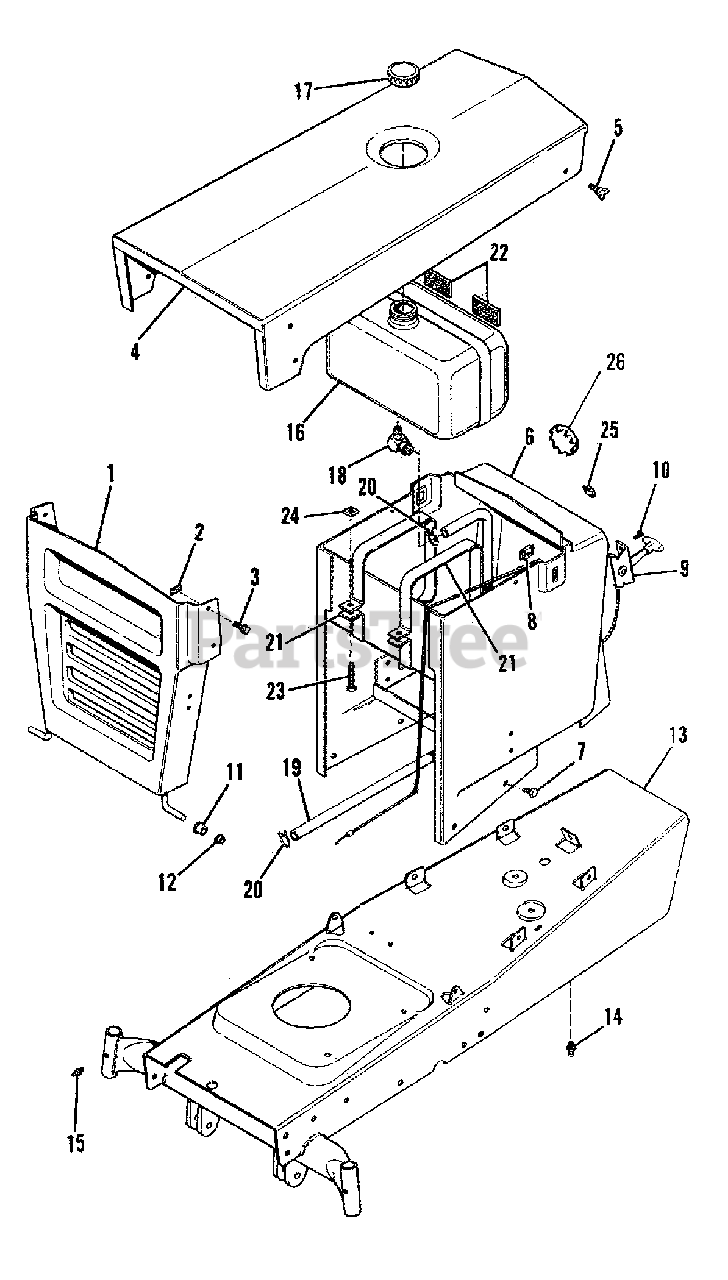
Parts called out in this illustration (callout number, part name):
1	GRILL ASSEMBLY
3	SCREW, Flange, 1/4-20 x 3/4" Large
5	SCREW, Thumb
6	DASH ASSEMBLY
7	SCREW, Taptite, 1/4-20 x 3/8 " Large
8	NUT, Retainer
10	SCREW, Taptite, 1/4-20 x 3/8 " Large
12	FASTENER, Pushnut
13	FRAME ASSEMBLY
14	FITTING, Grease
15	FITTING, Grease
16	TANK, Fuel
17	CAP, Fuel Tank
18	ELBOW, 90 Degrees
19	HOSE, Fuel
20	CLAMP, Hose
21	STRAP, Tank
22	GASKET, Felt
23	SCREW, Machine, 1/4-20 x 1-1/2" Large
24	NUT, Square, 1/4-20
25	BUTTON, Plug
26	BUTTON, Plug
